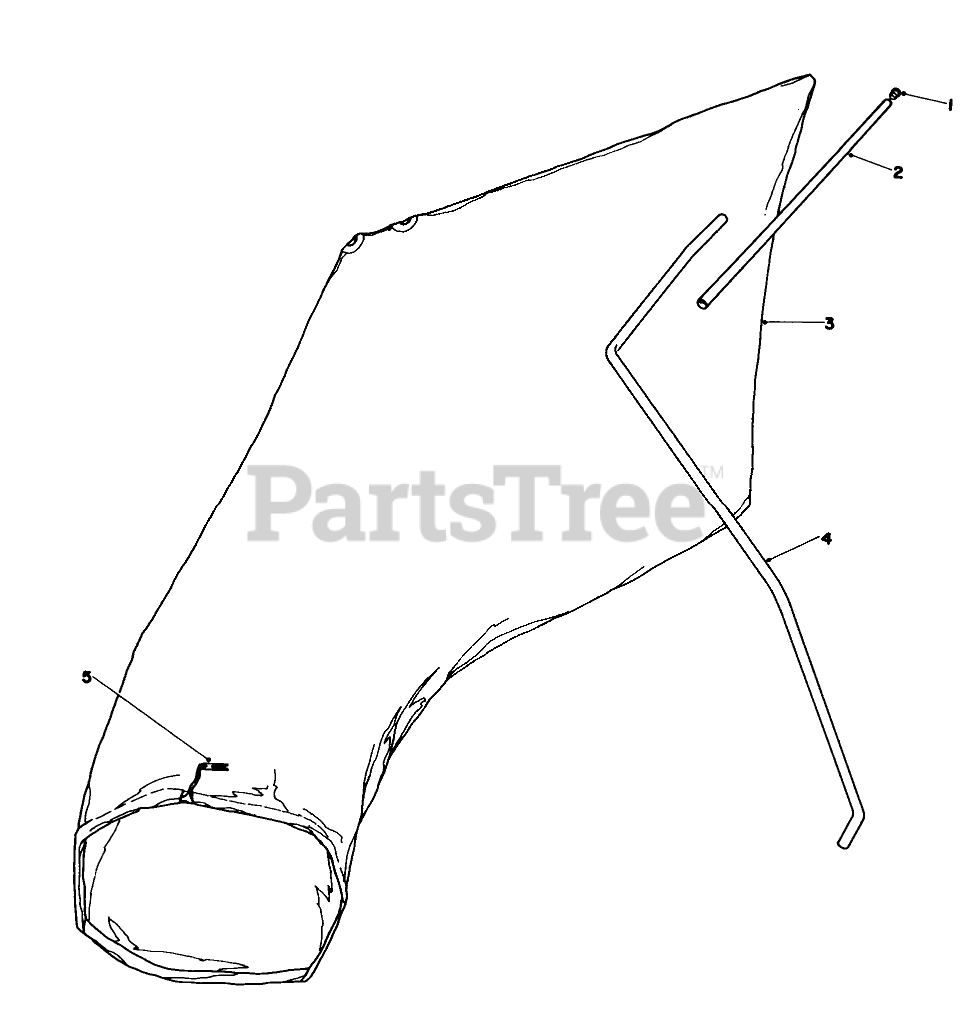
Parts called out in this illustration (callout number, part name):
2	BAG HANGER TUBE
3	Bag (Incl. Ref. #5)
4	HANGER ROD
5	BAG CORD FASTENER
